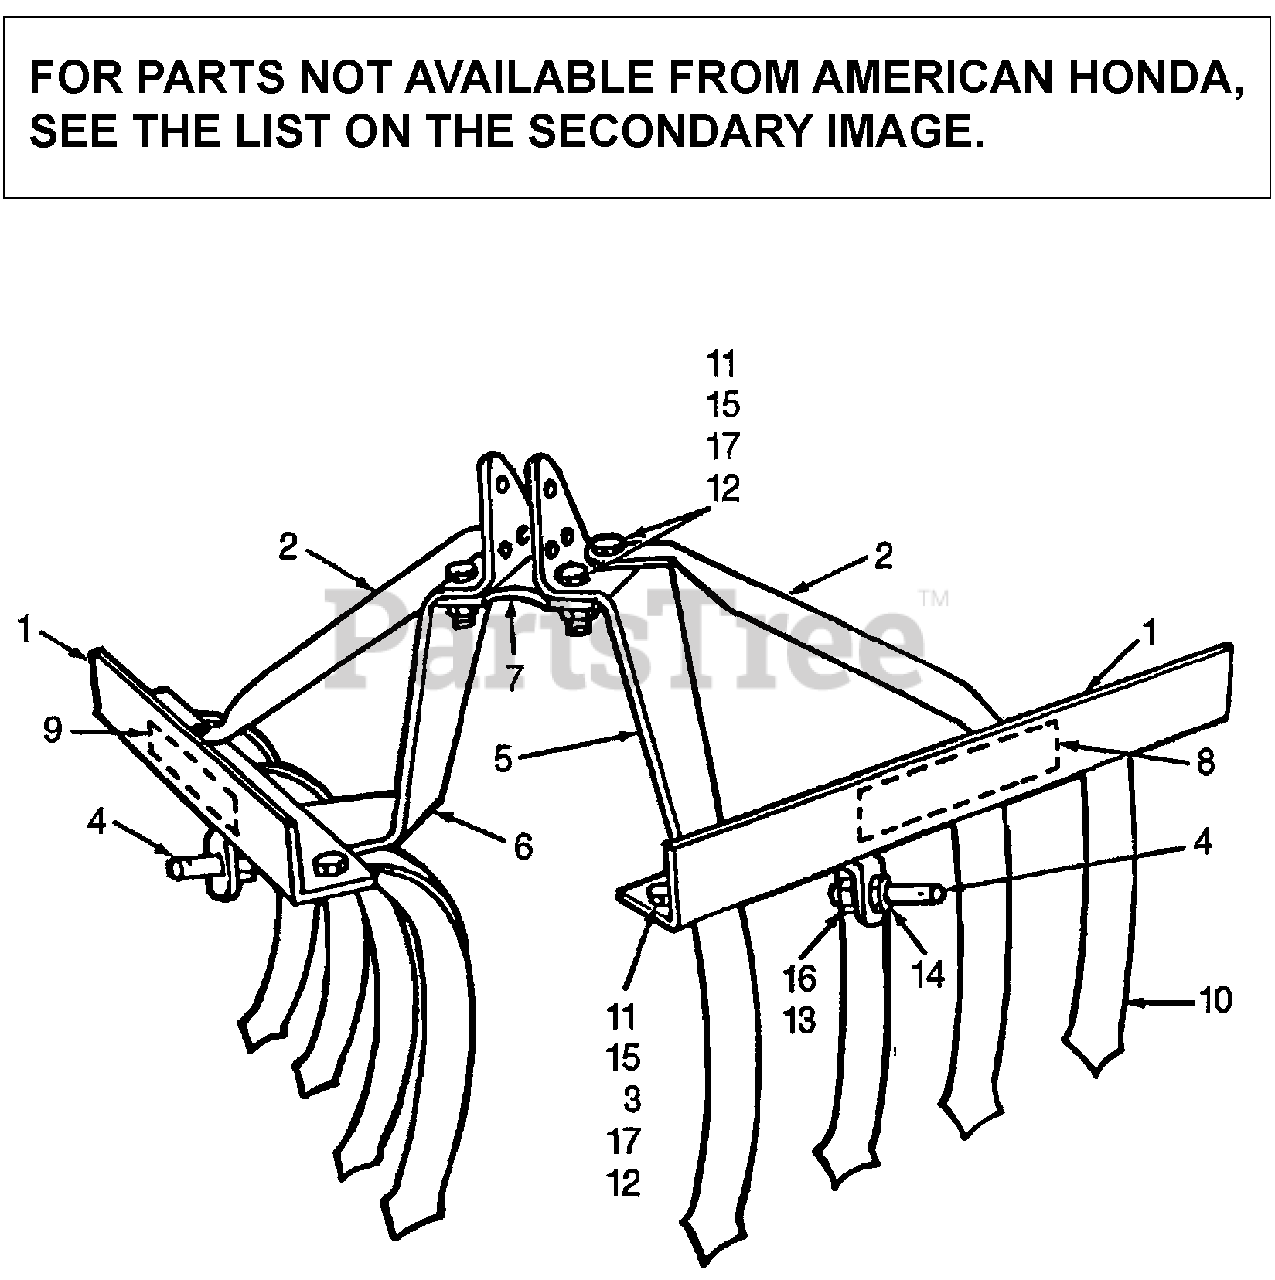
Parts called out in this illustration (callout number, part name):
3	WASHER, SPECIAL (3/8" THICK)
4	PIN, LINK (LOWER)
10	SHANK, SPRING (NOT AVAILABLE)
